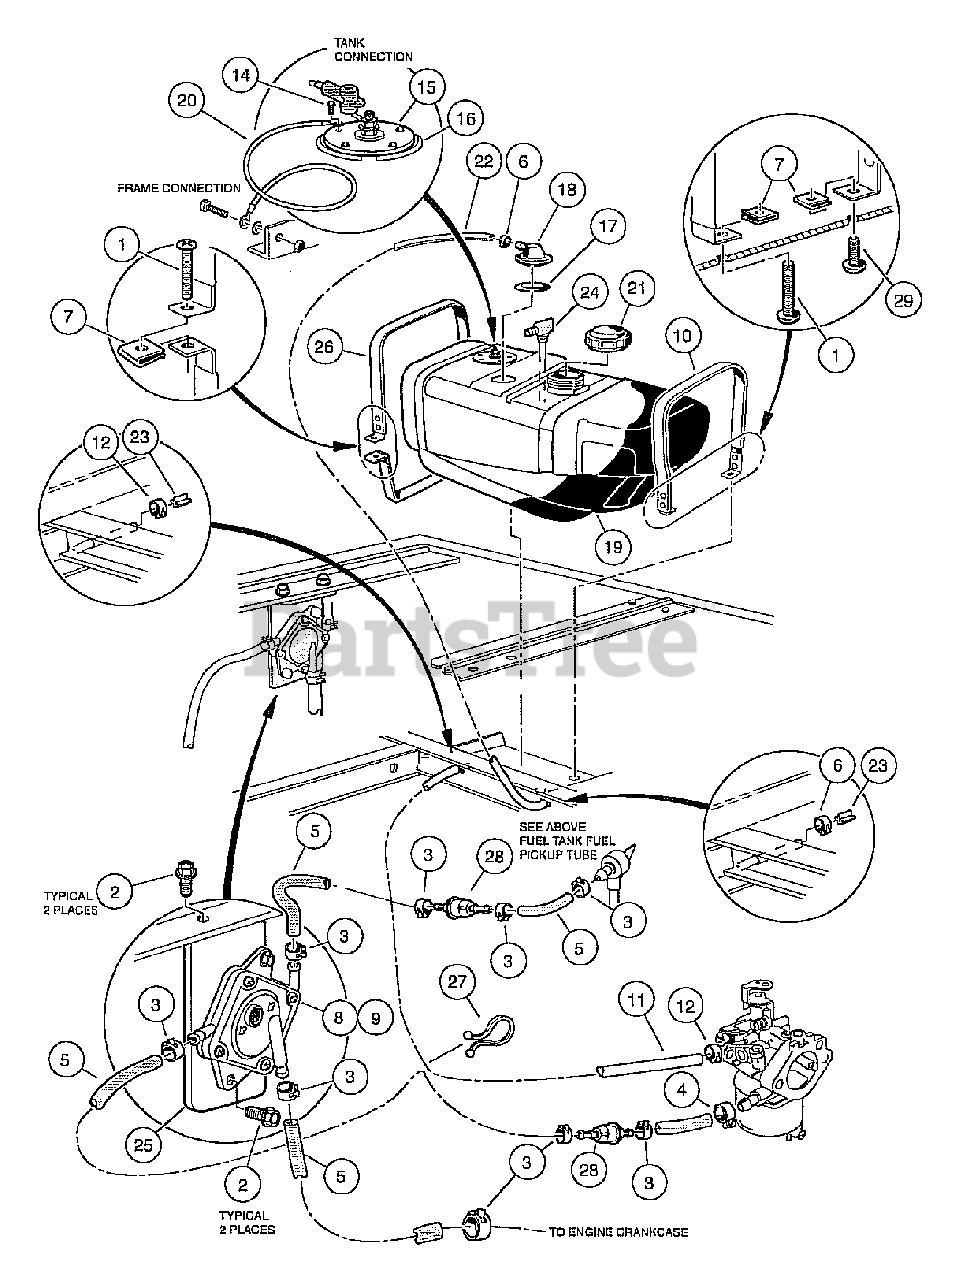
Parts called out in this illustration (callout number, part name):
1	Screw, 1/4-20 X 2.00 Phl.truss
2	Screw, 1/4 X 0.625 Hex-Head
3	Clamp, 0.460 Red Hose
4	Clamp, 3/8" Hose (screw type)
5	Fuel Line
6	Clamp, 0.301 ID Hose
7	Nut, 1/4-20 Speed
8	Pump, Impulse Fuel
9	Kit, Impulse Pump Rebuild
10	Fuel Strap Assembly Rear
11	Tank Kit w/Sending Unit
12	Clamp, 0.301 ID Hose
13	Fuel Tank with Sending Unit
14	Screw, #10-16 Hex Head Hi-lo
15	Sending Unit, Fuel Level
16	Gasket, Sending Unit
17	Insulation Grommet
18	Vent, Fuel Tank
19	Fuel Tank with Vent and Sending Unit Hole
20	Wire Assembly #16 Black
21	Cap, Fuel Tank, Gasoline
22	Tube, Carburetor Air Vent
24	Fuel Pickup w/Shut-Off Valve
25	Mount, Fuel Pump
26	Fuel Strap Assy, Front
27	Clamp, Plastic Tie
28	Filter, Fuel, 30 Micron
29	Screw, 1/4-20 X .75 Trs Hd Mch
